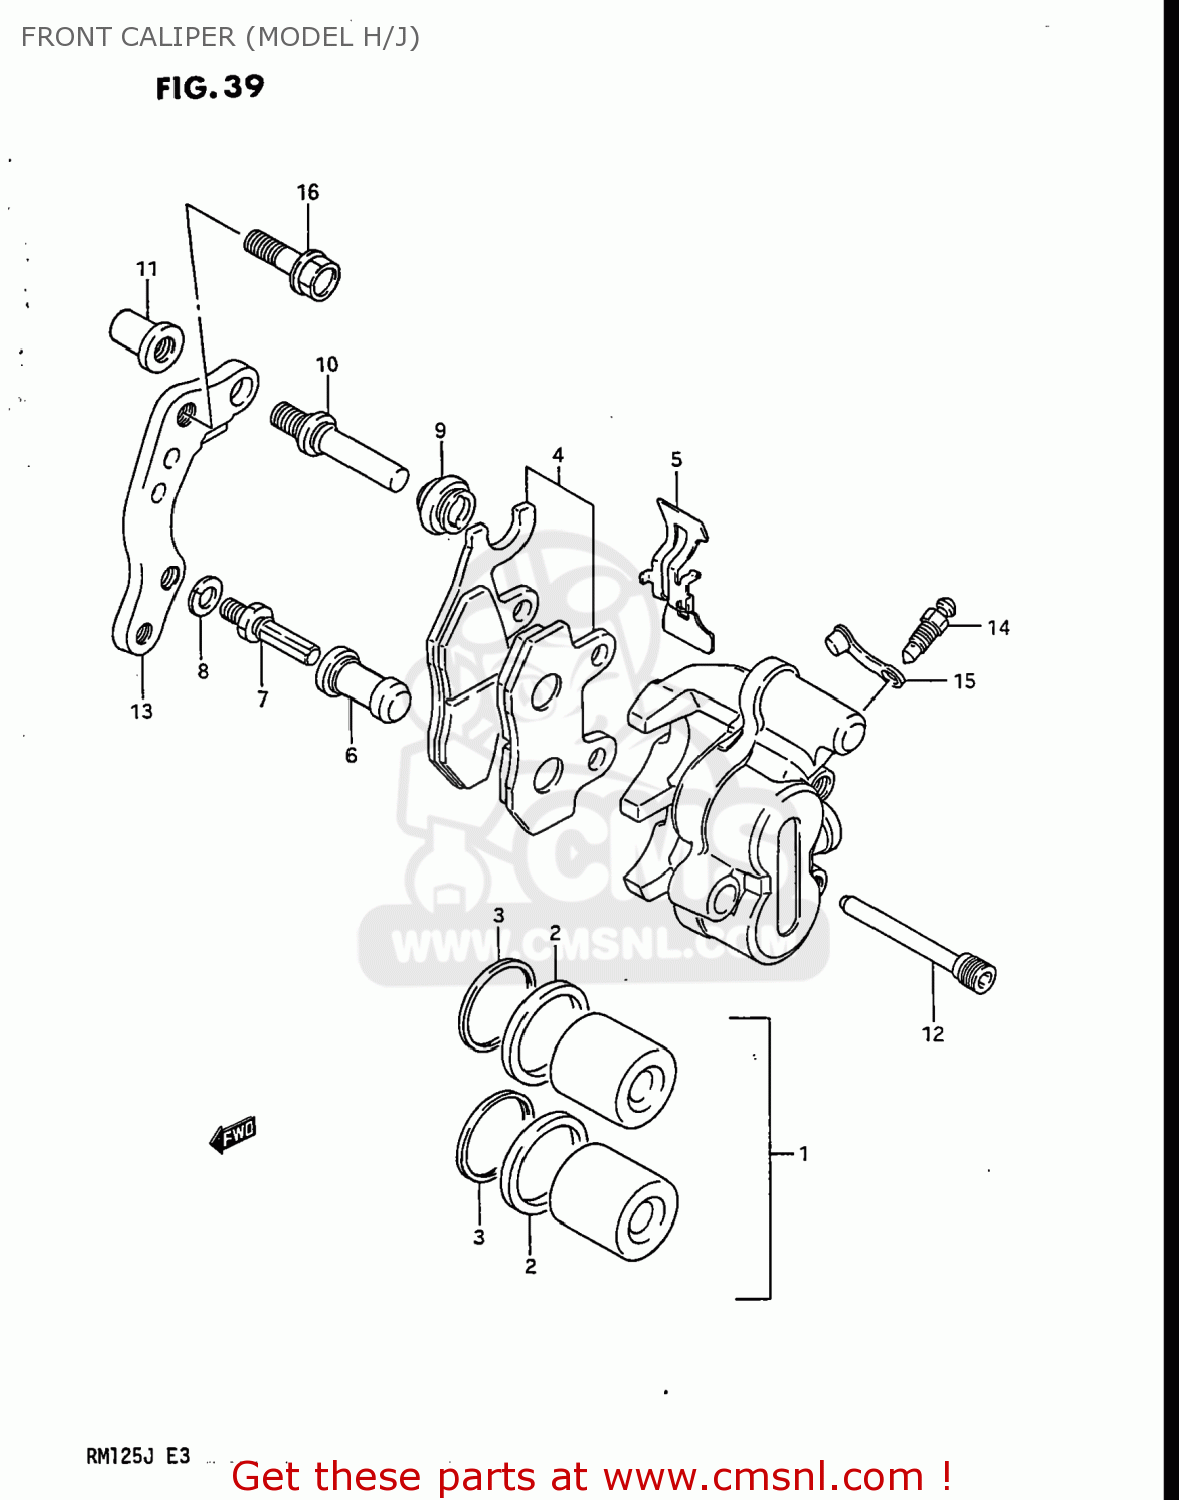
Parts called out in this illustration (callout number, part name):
1	PISTON SET
2	SEAL,PISTON
3	SEAL,DUST
4	PAD SET (MCA)
5	SPRING
6	BOOT
7	BOLT,PIN
8	WASHER,WAVE
9	BOOT
10	PIN,SLIDE
11	NUT
12	PIN,HOLDER
13	BRACKET
14	BLEEDER
15	CAP,BLEEDER
16	BOLT(8X24)
